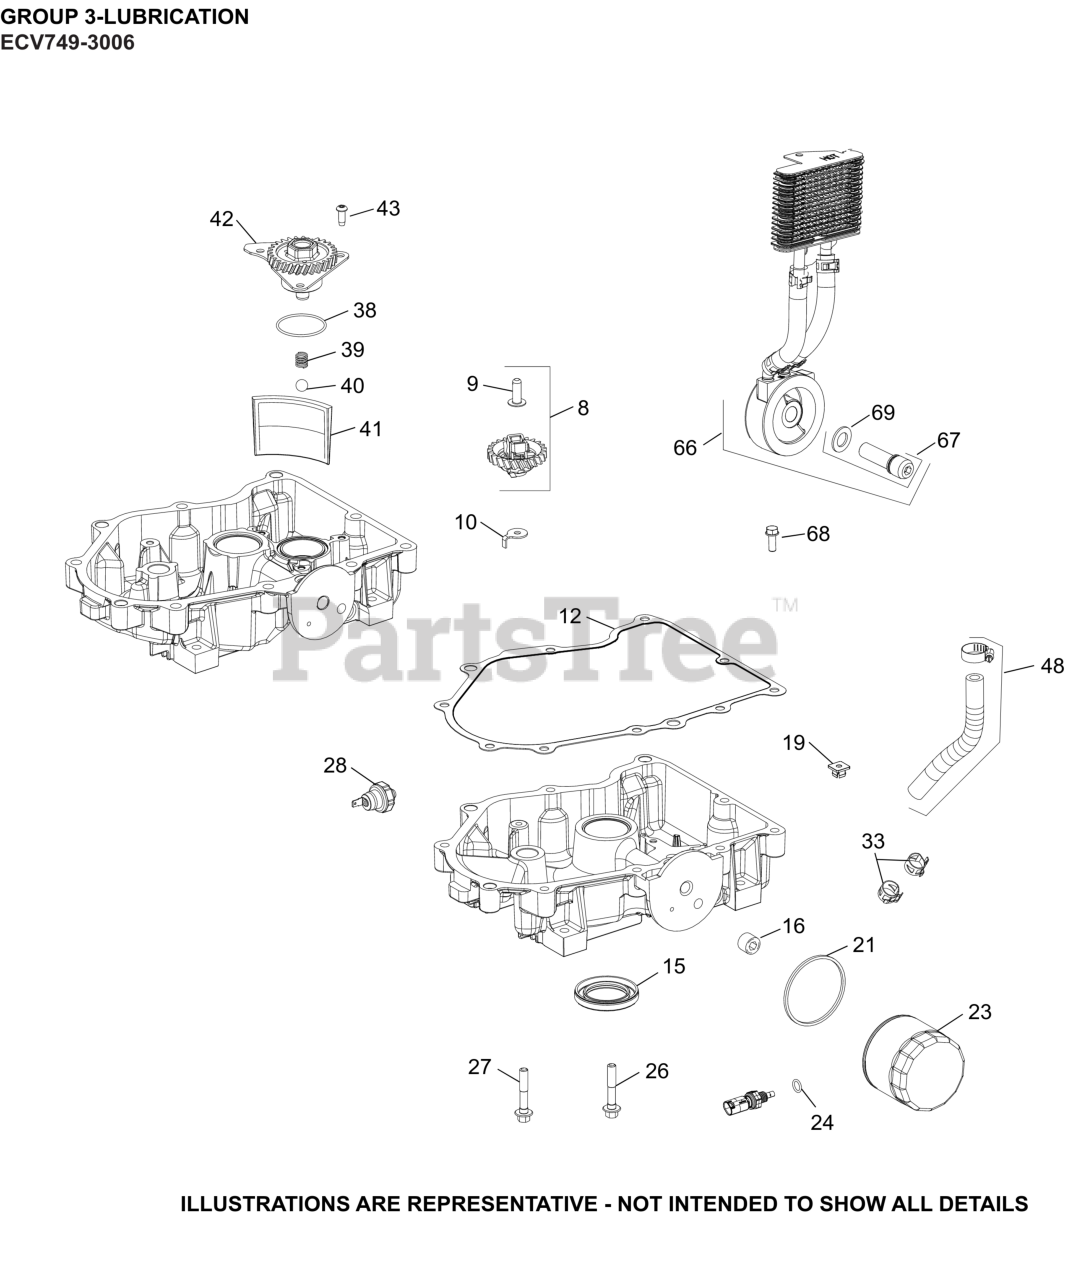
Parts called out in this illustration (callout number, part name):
8	KIT, GOVERNOR GEAR W/PIN
9	PIN, GOVERNOR REGULATING
10	TAB, LOCKING
12	KIT, OIL PAN GASKET
16	PLUG, PIPE CTSK 3/8"
19	NUT, PLASTIC - BLACK
21	O-RING, OIL COOLER
23	OIL FILTER
24	O-RING (.5" DIA)
26	SCREW, HEX FLANGE
27	SCREW, FLG M8X1.25X45
28	SENSOR, OIL PSI
33	CLAMP, HOSE LOW PROFILE
38	O-RING (1.78" DIA)
39	SPRING, COMPRESSION
40	PRESSURE RELIEF BALL
41	SCREEN, OIL
42	PUMP, OIL ASSEMBLY
43	SCREW, BUTTON HEAD
48	KIT, HOSE 140MM
66	KIT, OIL COOLER
67	KIT, OIL FILTER NIPPLE
68	SCREW, HEX HEAD
69	WASHER, FLAT
NI	PAN, ASSEMBLY OIL (SERVICE)
NI	SHAFT, GOVERNOR GEAR
